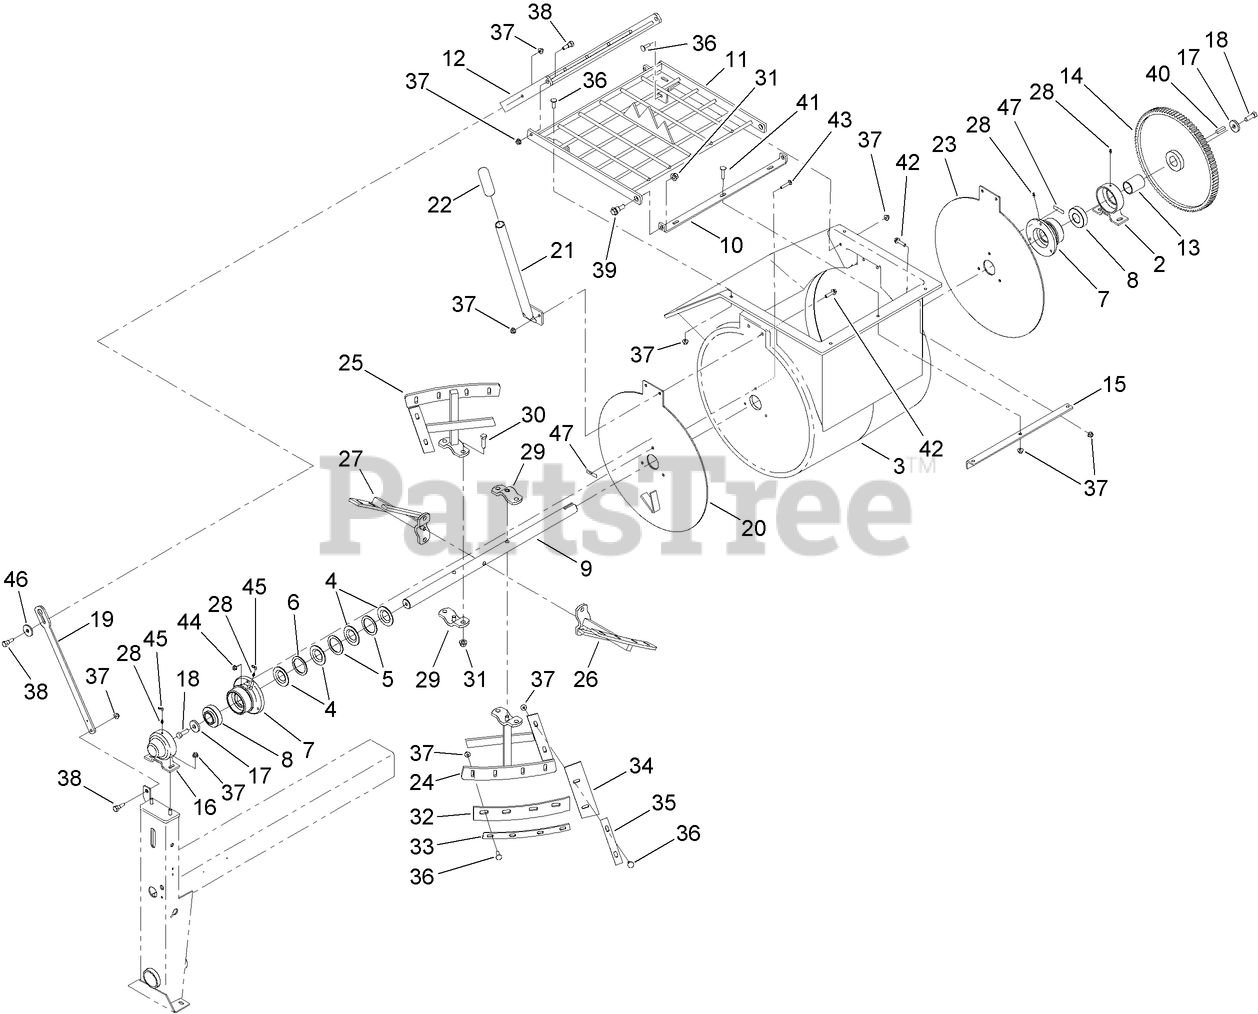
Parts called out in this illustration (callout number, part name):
2	TRUNNION
4	SEAL-DRUM
5	WASHER-FLAT
6	WASHER-SPLIT
7	HOUSING-BEARING
8	BEARING-BALL
9	SHAFT-DRUM
10	MOUNT-GUARD
11	GUARD-STATIONARY
12	GUARD-DRUM
13	SPACER-SHAFT
14	GEAR-94 TEETH
15	SUPPORT-GUARD
16	TRUNNION-CAPPED
17	WASHER-FLAT
18	SCREW-HH
19	BAR-GUARD, LIFTER
20	END-DRUM
22	GRIP-HAND
23	END-DRUM
28	FITTING-GREASE
30	SCREW-HH
31	NUT-LOCK
32	BLADE-RUBBER, LONG
33	BAR-BACKER, LONG
34	BLADE-RUBBER, SHORT
35	BAR-BACKER, SIDE
36	BOLT-CARR
37	NUT-HF, NI
38	BOLT-SHOULDER
39	SCREW-SHOULDER, HHF
40	KEY-SQUARE
41	SCREW-CARR
42	SCREW-HHF
43	SCREW-CARR
44	NUT-HF, NI
45	CAP-PLUG
46	Washer-Thrust
47	DECAL-GREASE
